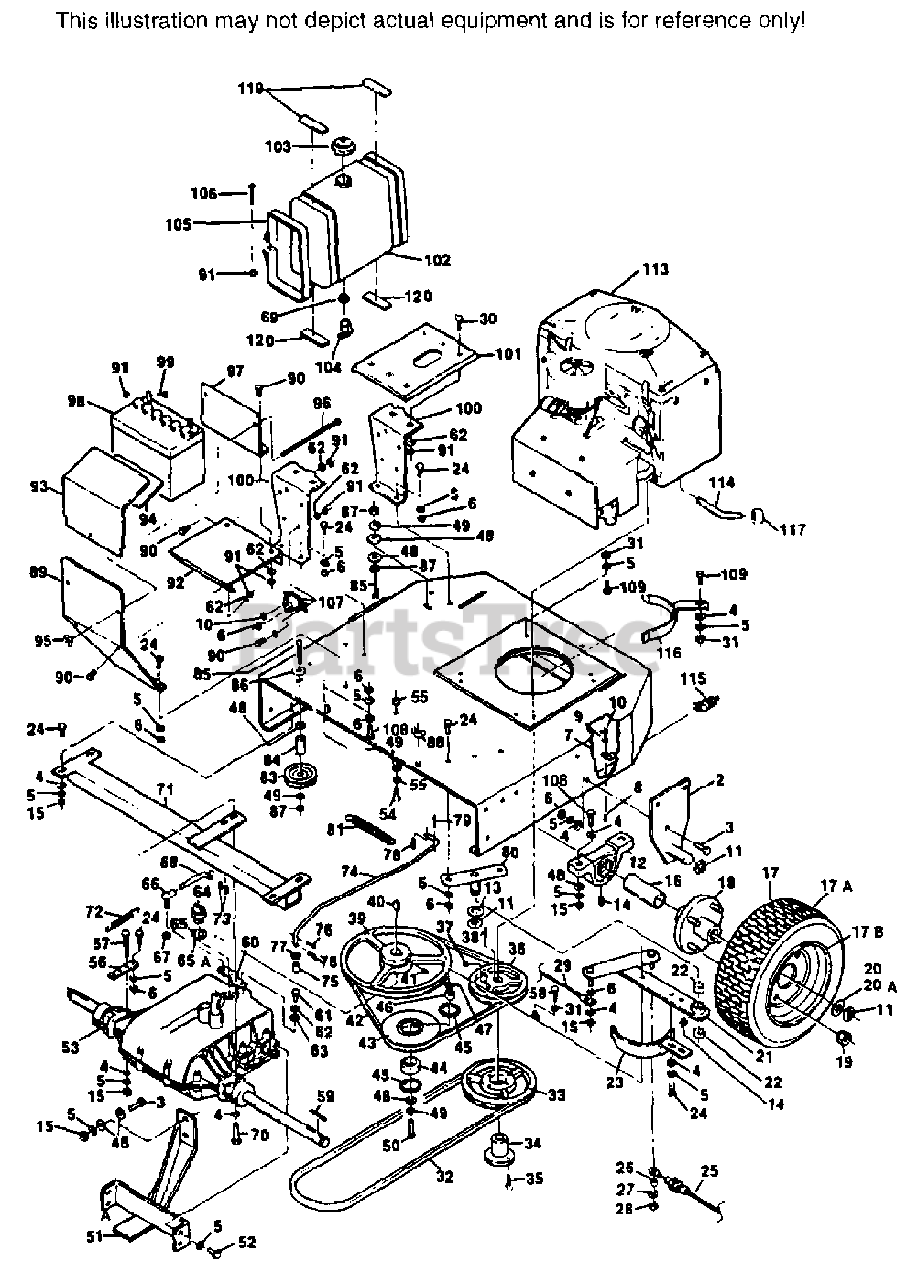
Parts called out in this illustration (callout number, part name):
2	HITCH BRACKET
4	WASHER, 11/32 X 11/16 X 16 GA.
7	CLAMP
9	LOCKWASHER, #10 EXT TOOTH
11	RETAINING RING, 1 EXT. "E"
12	BEARING, PILLOW BLOCK 1"
13	WASHER 49/64 X 1 1/4 X 16 GA.
14	GREASE FITTING, STR., 1/4-28
16	SPACER - LH AXLE
17	DRIVE WHEEL ASSEMBLY
17A	TIRE, 18 X 8.50-8, 4 PLY
17B	RIM
19	BOLT AND NUT
20	WASHER, 1-1/16 X 1-3/4 X 12 GA.
20A	WASHER, 1-1/16 X 1-3/4 X 18 GA.
21	IDLER ARM(INCLUDES 14 & 22)
22	BRONZE BEARING
23	BELT GUIDE
25	FOOT CABLE ASSEMBLY
26	SLEEVE, FOOT CABLE
27	WASHER, 9/32 X 5/8 X 16 GA.
29	BRAKE CABLE
31	HEX NUT, 5/16-18, ELASTIC STOP
32	BELT, BLADE DRIVE SM61
33	PULLEY, MOWER DRIVE(INCL. 34 & 35)
34	TAPER HUB
36	PULLEY
38	KEY, 1/4 X 1/4 X 2-1/2"
39	PULLEY, TRANSAXLE
40	KEY, HI PRO #9
42	BELT, TRANSAXLE DRIVE
43	PULLEY, IDLER
44	BEARING, IDLER PULLEY
45	RETAINING RING, 1-9/16" INT. BASIC
46	SLEEVE, TRANSMISSION IDLER BEARING
47	SPACER, TRANSMISSION IDLER
48	WASHER, 25/64 X 15/16 X 12 GA.
51	TRANSAXLE PROTECTOR
53	TRANSAXLE
56	SPACER, TRANSAXLE
59	KEY, 1/4 X 1/4 X 2-1/2" PLATED
60	SHIFT LEVER
61	HEX HD. BOLT, 1/4-28 X 3/4 GRD. 8
63	WASHER, 17/64 X 7/8 X 1/8 H.T.
64	NEUTRAL SAFETY SWITCH
65	FIBER WASHER, .010
65A	FIBER WASHER, .020
66	BALL JOINT
67	HEX LOCK NUT, 3/8-24
68	SHIFT CONNECTOR ROD
69	BUSHING, FUEL TANK VALVE
71	TRANSAXLE SUPPORT
72	SPRING, BRAKE RETURN
73	HAIR PIN, SMALL
74	BLADE CLUTCH ROD
75	SLEEVE
77	WASHER, 33/64 X 1 X 16 GA.
78	HAIR PIN, LARGE
80	PIVOT BASE WLD.
81	SPRING, BELT CLUTCH
83	PULLEY, BRAKE CABLE
84	SPACER, PULLEY
86	WASHER, 13/32 X 1-1/2 X 7 GA.
88	WING NUT, 3/8-16
89	BATTERY MOUNTING BRACKET
92	BATTERY SHELF
93	BATTERY COVER
94	BATTERY COVER PAD
95	WING NUT, 1/4-20
96	CARRIAGE BOLT, 1/4-20 X 6"
97	BATTERY CLAMP
100	TANK MTG. BRACKET(VERTICAL)
101	SUPPORT, FUEL TANK(HORIZONTAL)
102	FUEL TANK(INCL. 103, 104, & 132)
103	FUEL TANK CAP
104	FUEL SHUT-OFF VALVE
105	FUEL TANK STRAP
107	SOLENOID
113	ENGINE, 18 HP KOHLER
114	OIL DRAIN EXTENSION
115	SAFETY SWITCH, BLADE CLUTCH
116	BELT GUIDE WELDMENT
117	PIPE CAP, 3/8 NPT
119	PAD, STRAP CUSHION
120	PAD, TANK SUPPORT
